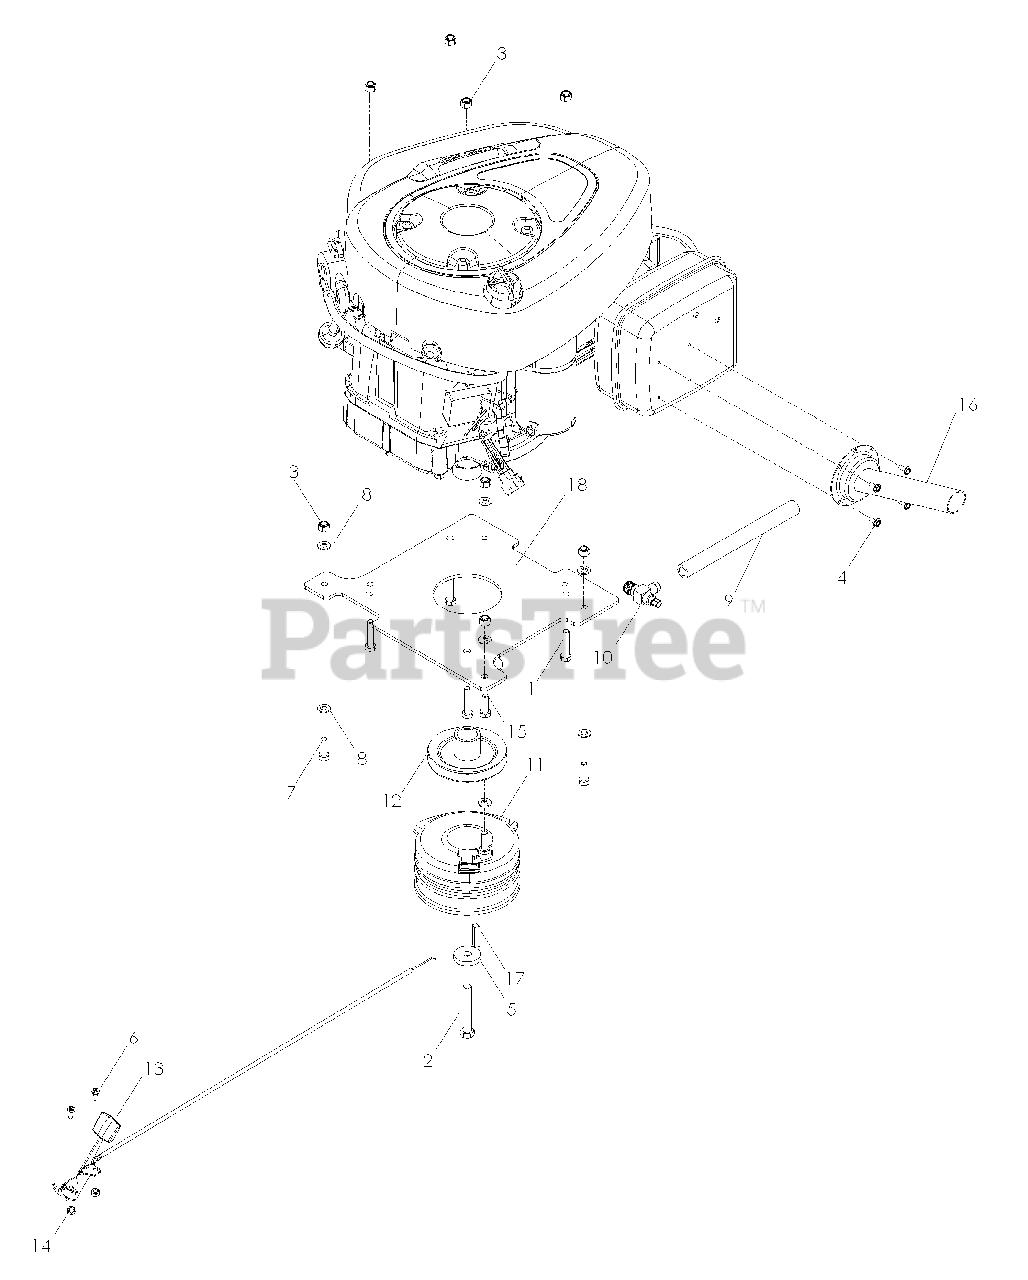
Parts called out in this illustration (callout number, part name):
1	HCS 5/16C X 2-3/4
2	HCS 7/16-20 X 2-3/4
3	NUT 5/16 NYLOC
4	SCREW, TAP #10-16 X 1/2
5	WASHER .43X1.38X.25
6	SCREW #10-24 X 5/8
7	HCS 5/16C X 1
8	FLAT WASHER 5/16 SAE
9	OIL DRAIN HOSE
10	OIL DRAIN
11	ELEC. CLUTCH
12	ENGINE PULLEY
13	THROTTLE CABLE
14	NUT 10-24 NYLOC
15	CAPSCREW 5/16 X 1/1/2 HEX HEAD
16	MUFFLER EXT.(PAINTED)
17	KEY, 1/4 SQ X 1 1/4
18	PLATE, ENGINE MOUNT BLUE
